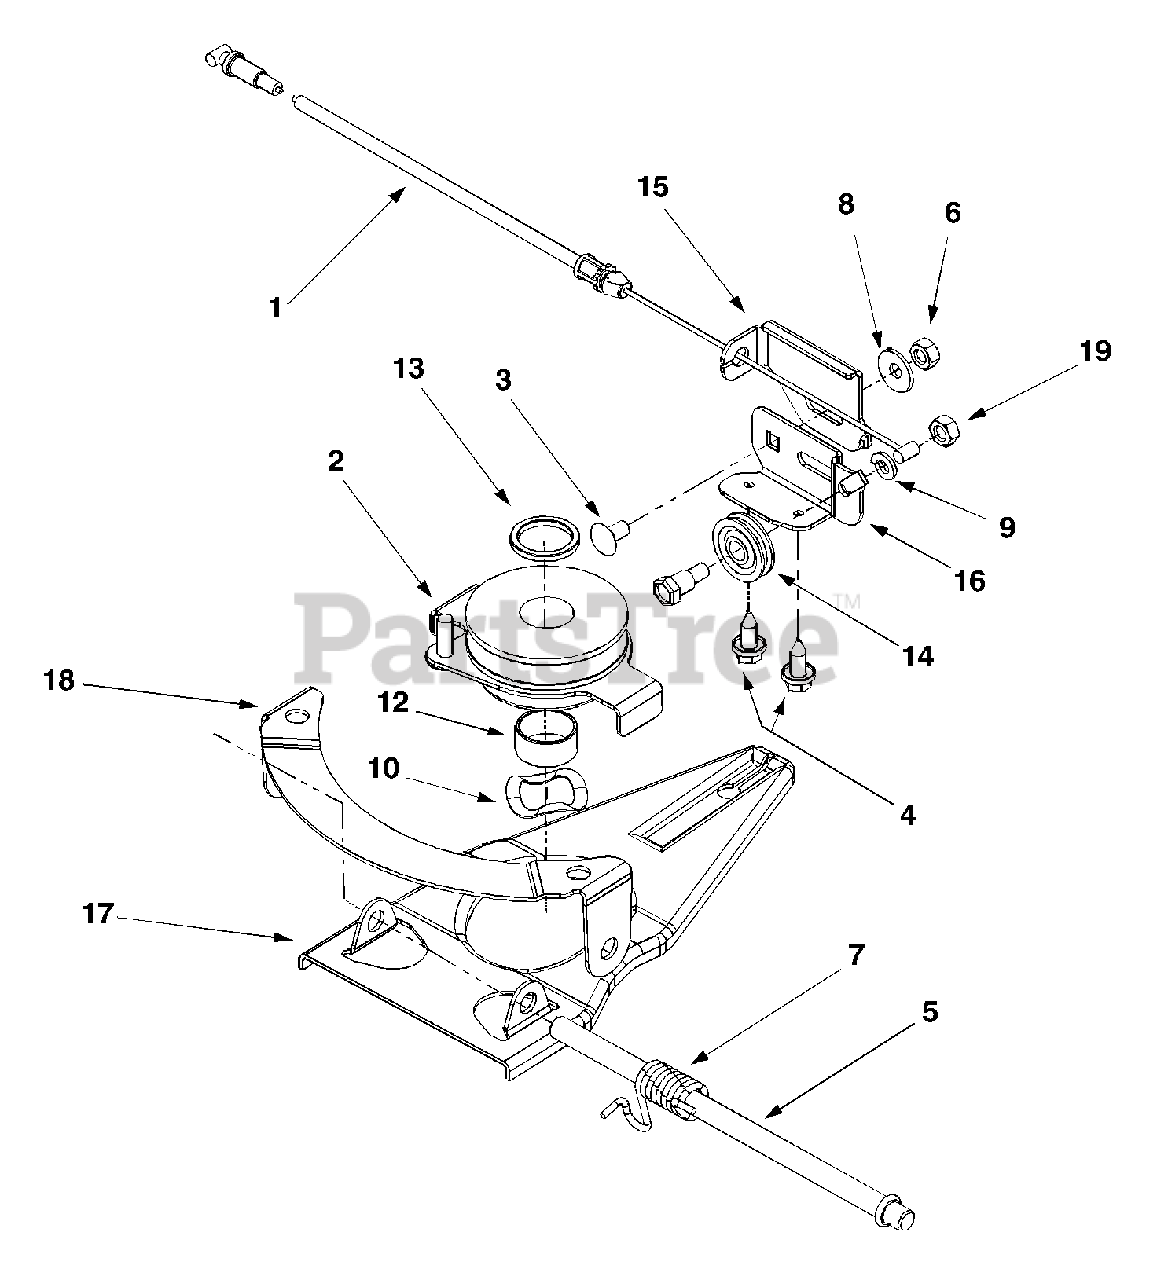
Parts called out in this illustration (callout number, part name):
1	Speed Selector Cable, 53"
2	Multi-speed Pulley Assembly
3	Carriage Bolt, 1/4-20 x. 5
4	Self-tapping Screw, 1/4-20 x .625
6	Nut, 1/4-20
7	LH Torsion Spring
8	Bell Washer, .265 x .75 x .062
9	Lock Washer, 1/4
10	Wave Washer, 1.38 x .88 x .029
12	Sleeve Spacer, .88 ID x 1 OD x .48
13	Sleeve Spacer, .88 ID x 1.13 OD x .12
14	Cable Roller
19	Hex Nut, 1/4-20
